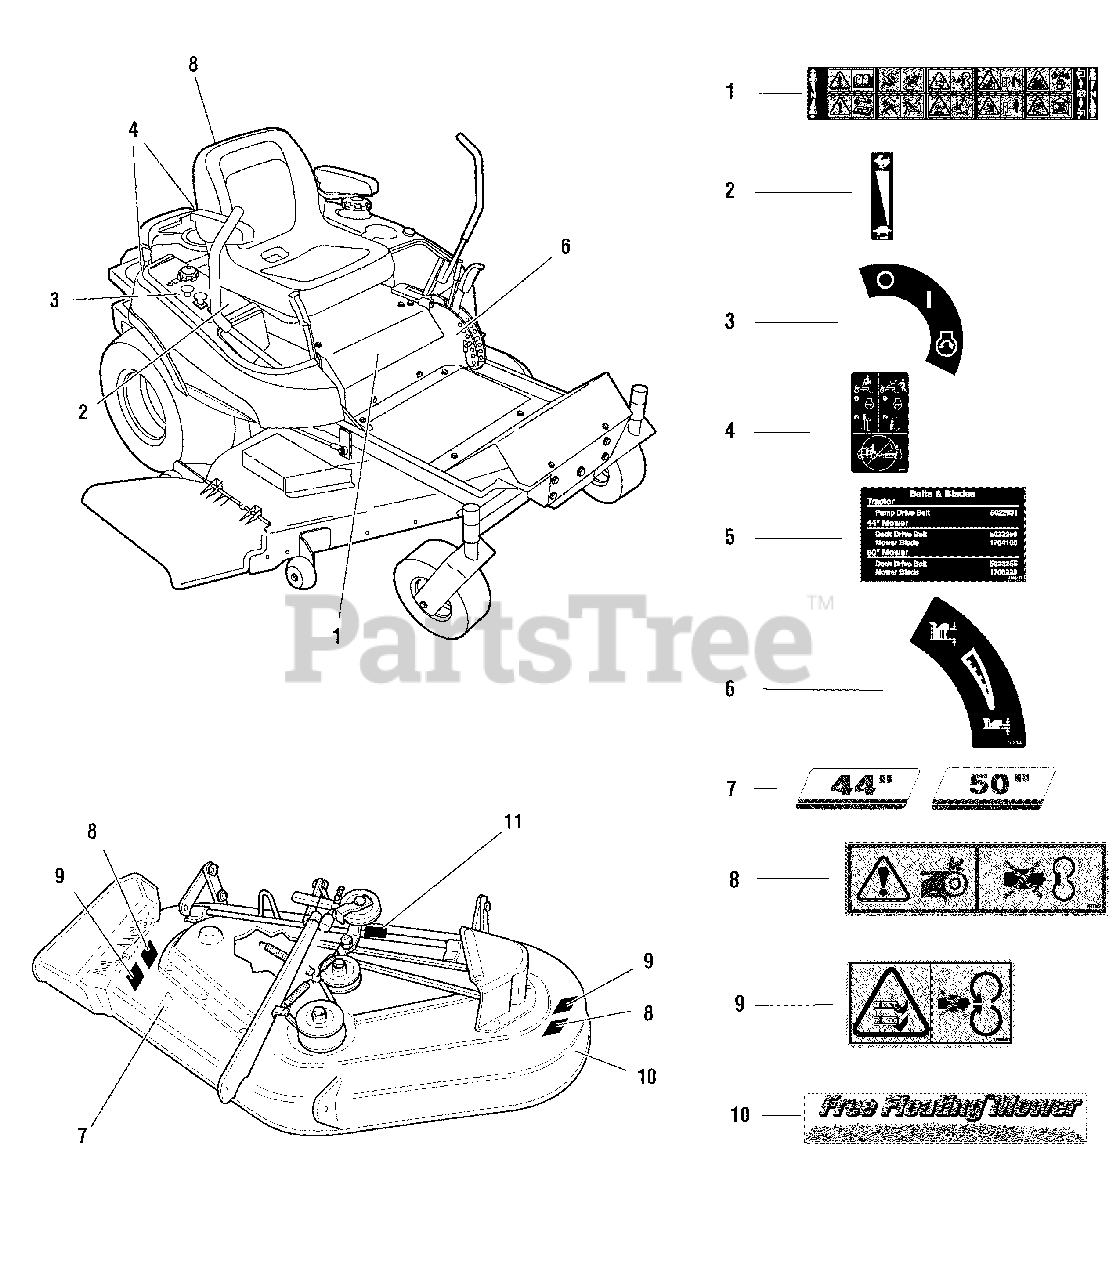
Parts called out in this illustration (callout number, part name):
1	DECAL, MAIN, CE
2	DECAL, THROTTLE CONTROL
3	DECAL, IGNITION SWITCH
4	DECAL, TRANSAXLE RELEASE
5	DECAL, BELT & BLADE, CONS Z
6	DECAL, HEIGHT OF CUT
7	DECAL, 44"- SILVER ON BLACK W/STRIPE
7	DECAL, 50"- SILVER ON BLACK W/STRIPE
8	DECAL, CE DANGER
9	DECAL, DANGER ROTATING BLADE SYMBOLS
10	DECAL, DANGER, CE
11	DECAL, FREE FLOATING MOWER - SILVER
12	TAG, PRINTED SERIAL
13	DECAL, HYDRAULIC OIL, SAE 20W-50
